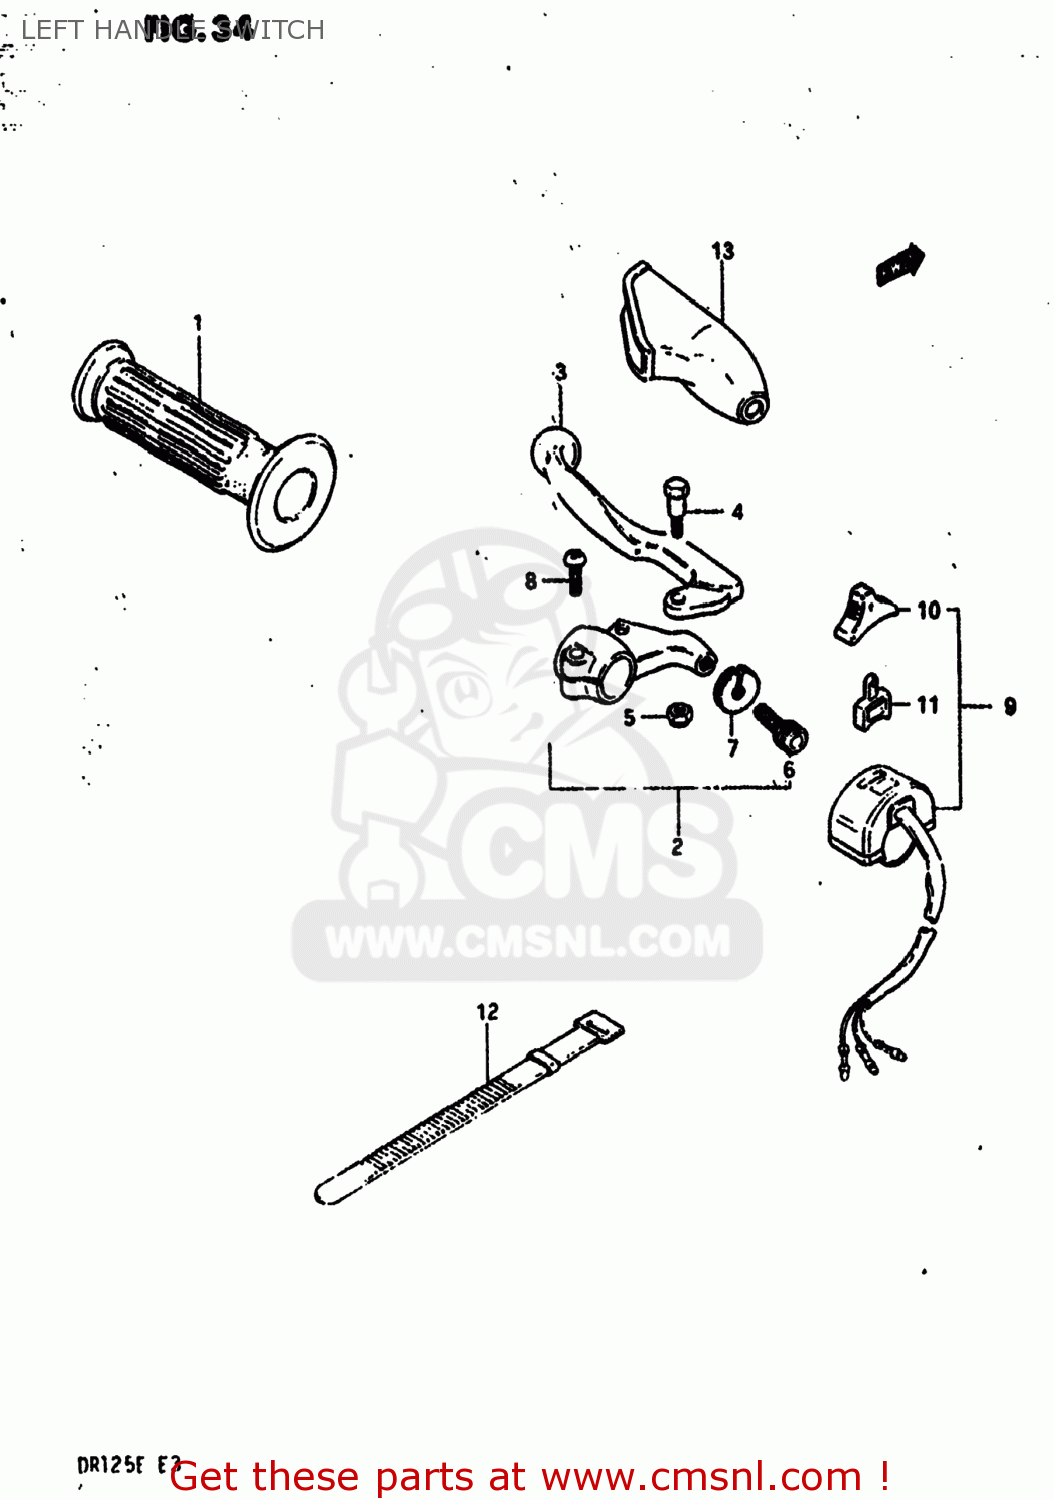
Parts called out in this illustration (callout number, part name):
1	GRIP,L
2	LEVER ASSEMBLY,CLUTCH
3	LEVER,CLUTCH
4	BOLT,LEVER
5	NUT 6MM
6	ADJUSTER,CABLE
7	NUT,CABLE ADJUSTER
8	SCREW
9	SWITCH ASSY,LIGHTING
10	KNOB,LIGHTING & DIMMER
11	BLOCK,LIGHTING/DIMMER
12	CLAMP(L:120)
13	COVER,CLUTCH LEVER
